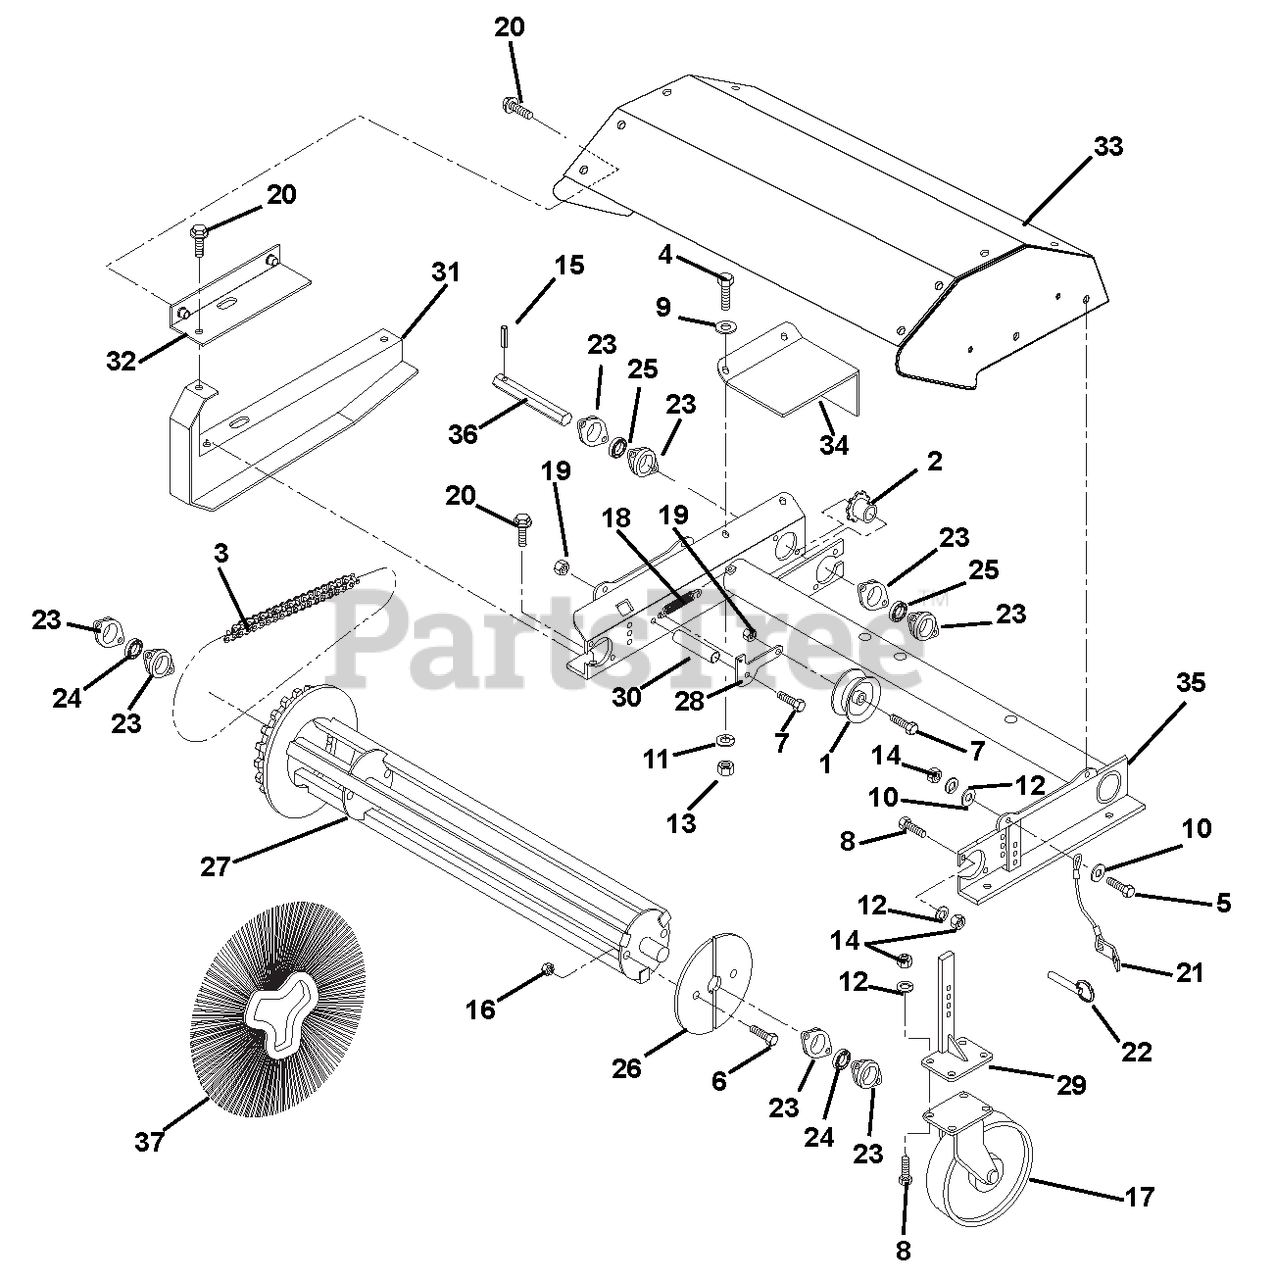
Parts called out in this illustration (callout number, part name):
1	CHAIN TIGHTENER
2	SPROCKET
3	CHAIN, ASS'Y #40X106 EDLS W/LK
4	@BLT-HEX .25-20X.75 GR5 YWZC
5	@BLT-HEX .31-18X1.00 GR5 YWZC
6	@BLT-HEX .31-18X2.25 GR5 YWZC
7	@BLT-HEX .38-16X1.50 GR5 YWZC
8	@BLT-HEX .31-18X.75 GR5 YWZC
9	@WSHR-FL-STL.281X.62X.065 YWZC
10	@WSHR-FL-STL.312X.734X.065 YWZ
11	@WSHR-LK .25X.062 REG YWZC
12	@WSHR-LK .31X.078 REG YWZC
13	@NUT-HEX .25-20 YWZC
14	@NUT-HEX .31-18 YWZC
15	PIN, SPRING LOK .187 X 1.25
16	NUT, LOK STAMPED .312-18 TINN.
17	WHL, 5 DIA.
18	SPRING, TENSION .50 X 3.0
19	@NUT-LK-CTR .38-16 YWZC
20	SCREW, GR 10.9 M6X1-20
21	LANYARD,.06 CAB.1.25X6,TYP C
22	PIN, HITCH, .38 X 2
23	FLANGE, SPHERICAL 2"
24	BRG 1.00 BORE, SPHER. OD.
25	BRG-BALL .884HEXX52MMX1.07
26	RETAINER PLATE (SET OF 2)
27	WELD, CORE C36TW
28	ARM, IDLER,BRM C36TW
29	WELD, CASTER LEG, C36TW
30	BSHG, .62X12 GA X.75
31	SHIELD,CHAIN, ARIENS
32	SHIELD, CHAIN,TOP,ARIENS
33	KIT, HD, ARIENS
34	SHIELD, INPUT, ARIENS
35	WELD, BFRM,ARIENS
36	SHAFT, HEX 20.5, W/HOLE
37	SET,SECTION,24",P,CONV.
